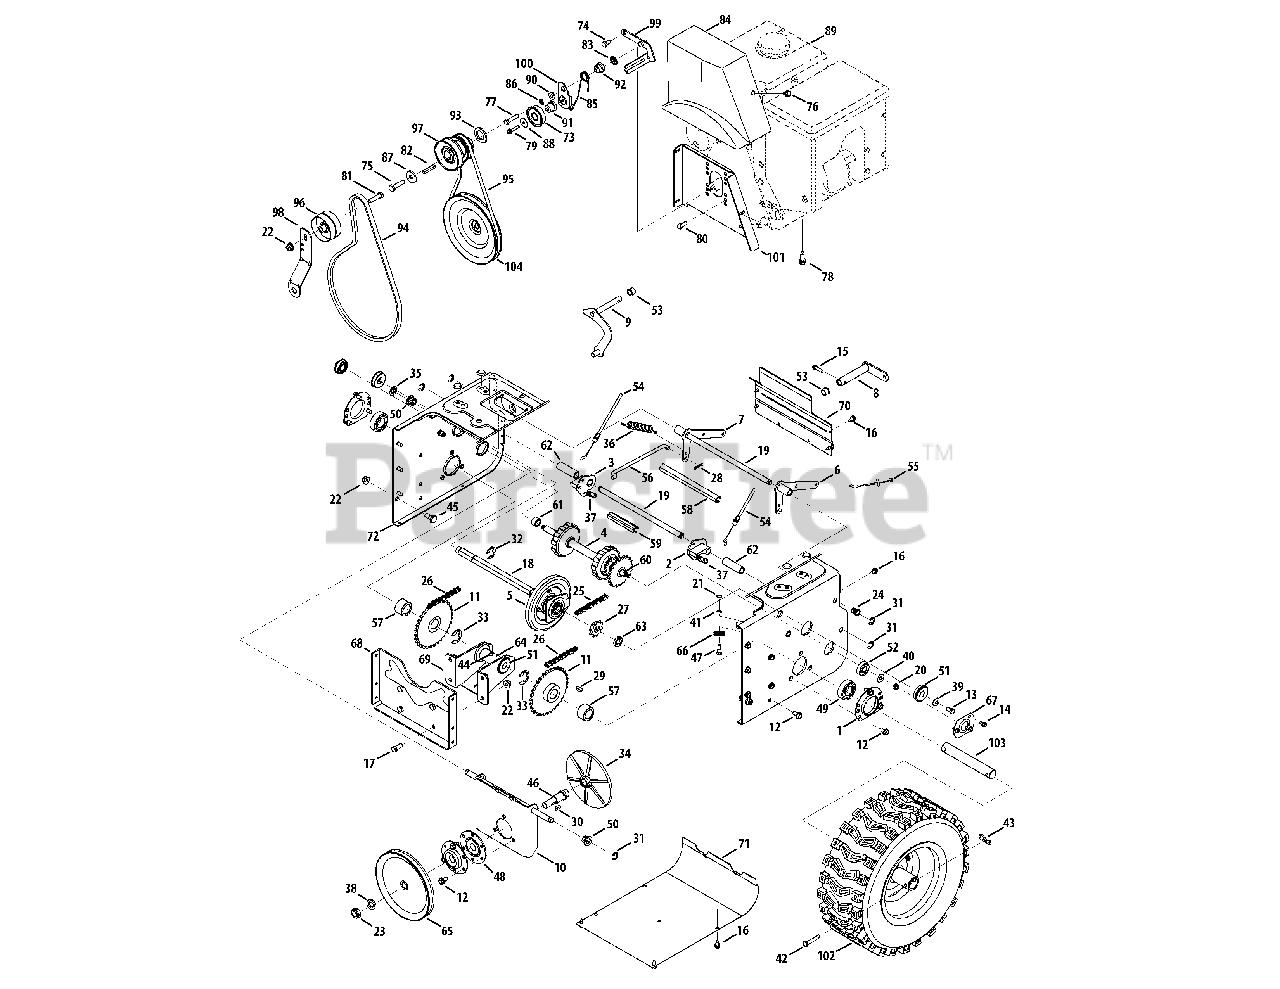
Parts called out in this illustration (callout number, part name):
1	Housing, Bearing
2	Dogg, Steering Drive, LH
3	Dogg, Steering Drive, RH
4	Shaft Assembly, Steering
5	Assembly, Friction Wheel
5	Wheel, Friction, Bonded
5	Screw, Hex Wash
6	Bracket, Auger Actuator
7	Bracket, Drive Actuator
8	Arm, Shift
9	Rod Assembly, Shift
10	Bracket, Friction Drive Support
11	Sprocket, 32T
12	TT Screw, 5/16-18 x .750
13	Screw, Hex Cap Lock,
14	Screw, Hex, 1/4-20 x .50
15	Screw, Hex, 1/4-20 x 1.00
16	Screw, Hex Wash.
17	Screw, Hex Cap, 3/8-16
18	Shaft, Hex Drive
19	Shaft, Actuator
20	Nut, Hex Insert Jam Lock
21	Nut, Hex, 1/4-28 GR5
22	Nut, Hx Flnge Insert Lk
23	Nut, Hx Insert Jam Lk
24	Nut, Insert 3/8-16
25	Chain, Endless, #41 x 36L
26	Chain, #420 x 40L
27	Sprocket, #41 x 10T
28	Pin, Internal Cotter
29	Key, Woodruff
30	Key, Hi-Pro, 3/16 x 5/8
31	E-Ring
32	Ring, Retaining
33	Ring, Retainer
34	Plate, Drive
35	Speed Nut, .500
36	Spring, Extension
37	Spring, Extension
38	Washer, Lock, 5/8
39	Washer, Bell., .34 x .872 x .06
40	Washer, .406 x .875 x .059
41	Washer, Lock, 1/4
42	Pin, Clevis
43	Pin, Internal Cotter
44	Fitting, Lube, 3/16 Drive
45	Screw, Shldr., .498 x .34
46	Spindle, Drive Plate
47	Screw, Hex Shldr., 1/4-28
48	Ass’y, Bearing/Housing
49	Bearing, Self Aligning
50	Bearing, Hex Flange
51	Bearing, Ball
52	Bush, Flg, .5625 ID x 1.375 x .4375
53	Bush, Flg, .5 ID x .627 OD
54	Cable, Steering
55	Cable, Auger Idler
56	Rod, Drive Clutch
57	Spacer, 1.01 x 1.50 x .93
58	Spacer, .49 x 7.865
59	Spacer, .49 x 3.545
60	Spacer, .566 x .87 x .190
61	Spacer, .566 x .87 x 1.25
62	Spcr., .514 x .632 x 2.44
63	Spacer, .675 x 1.0 x .23
64	Spcr, .6725 x 1.125 x 2.48
65	Pulley, Drive
66	Roller, Cable
67	Retainer Bracket
68	Bracket, Frame Support
69	Bracket, Axle Support
70	Cover, Upper Frame
71	Cover, Lower Frame
72	Trans Frame
73	Idler Pulley Assembly
74	Screw, Hex 5/16-24 x .75
75	Screw, Hex 3/8-24 x 1.25
76	Screw, Hx Wash Hd Tapp
77	Screw, Hex Cap, 5/16-24 x 1.50
78	Screw, 3/8-16 x 1.00
79	Screw, 1/4-20 x 1.25
80	Screw, Hex Cap, 5/16-24 x .875
81	Screw, Hex Cap, 3/8-16 x 1.75
82	Key, Square, 1/4 x 1.5
83	Nut, Push
84	Cover, Belt
85	Torsion Spring, .850 dia. x .333 lg.
86	Washer, Lock, 5/16
87	Washer, Flat, .406 x 1.25
88	Washer, Flat, .265 x 1.0 x .030
89	Engine Complete
90	Shoulder Spacer, .3175 x .500 x .094
91	Shoulder Spacer, .260 x .785 x .538
92	Shoulder Spacer, .340 x 1.00
93	Spacer, 1.02 x 1.63 x .1425
94	V-Belt, 4L x 44.60
95	V Belt, 3/8 x 36.68
96	Pulley, Flat Idler, 2.75 OD
97	Double Pulley, 3.25 x 2.75
98	Bracket, Auger Idler
99	Belt Keeper Bracket
100	Idler Drive Wheel Bracket
101	Belt Cover Bracket
102	Wheel Ass’y. - LH
102	Wheel Ass’y. - RH
102	Rim Assembly
102	Valve
103	Axle, Wheel, 45"
104	Auger Pulley, 10.0 x .5
